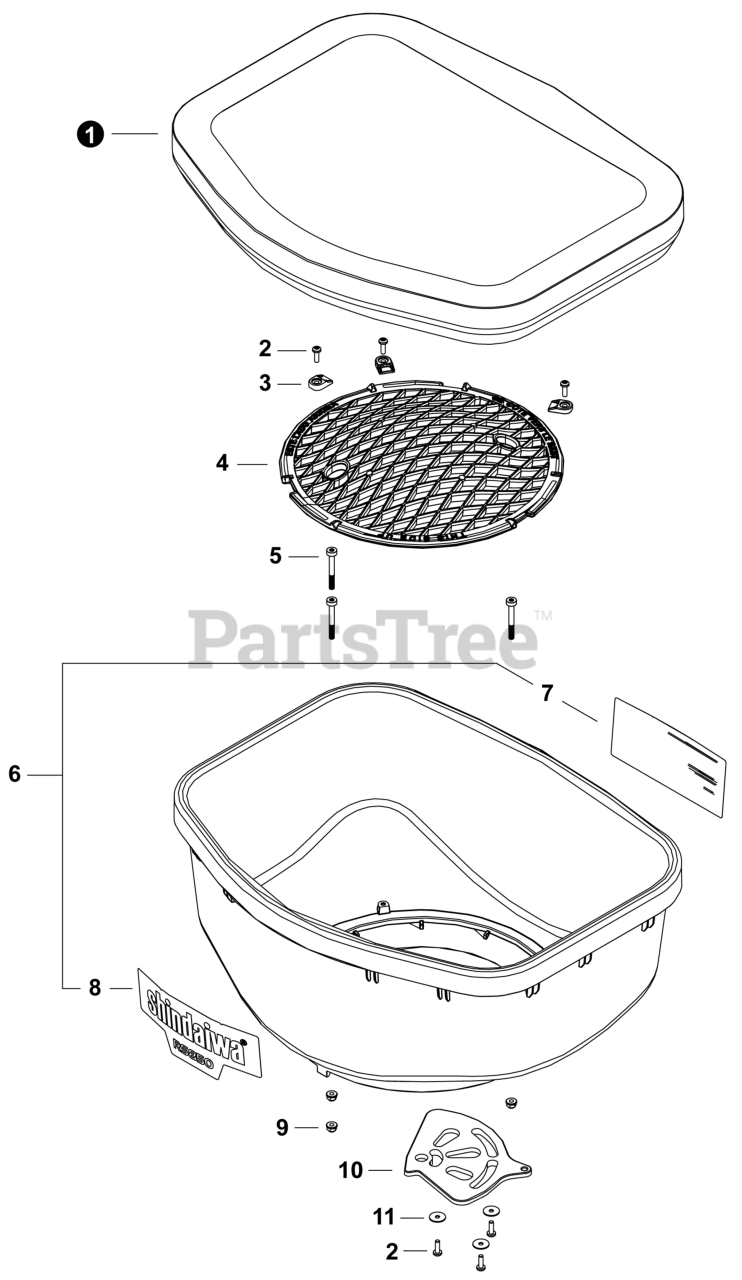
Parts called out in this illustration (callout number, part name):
1	COVER, HOPPER
2	BOLT, TORX 5x16
3	CLIPS, SCREEN
4	SCREEN, HOPPER
5	BOLT, M6 X 50MM
6	HOPPER ASSY
7	LABEL - OPERATION
8	LABEL - RS850
9	NUT, FLANGE M6
10	PLATE, REGULATOR
11	WASHER 5
